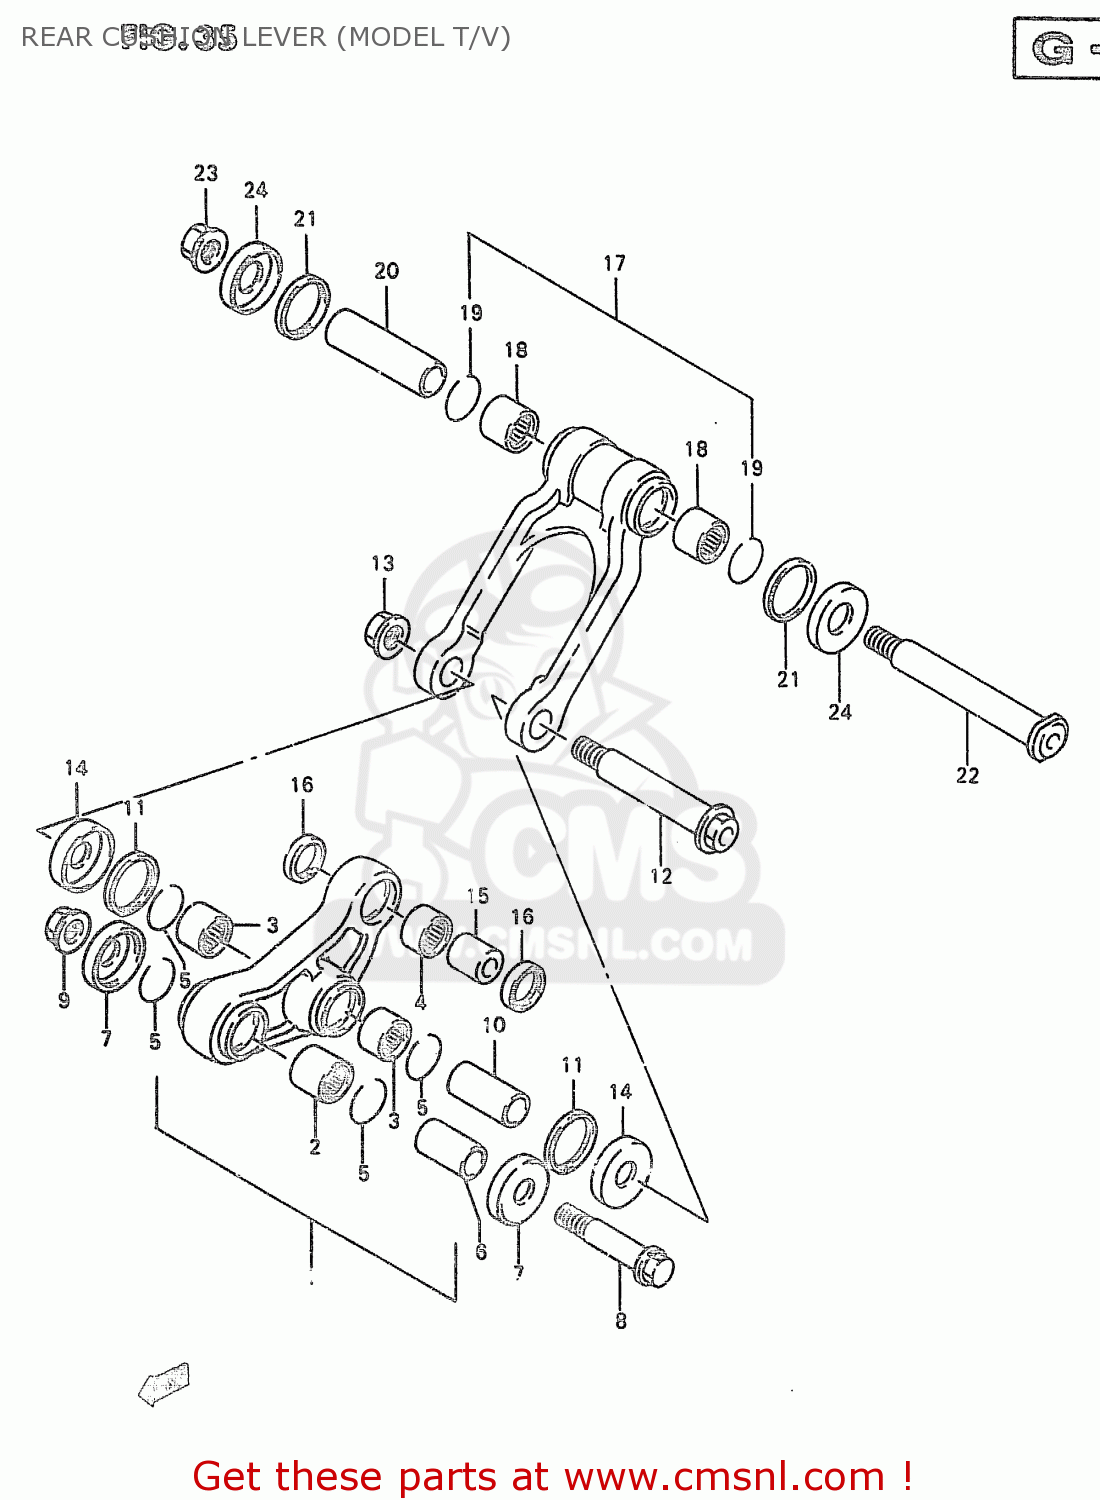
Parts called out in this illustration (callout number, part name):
1	LEVER SET,RR CUSHION
2	BEARING(20X27X25)
3	BEARING(22X28X20)
4	BEARING(20X26X12)
5	CIRCLIP
6	SPACER,RR CUSHION LEVER FR
7	SEAL,RR CUSHION LEVER FR DUST
8	BOLT,RR CUSHION LEVER FR
9	NUT 12MM
10	SPACER,RR CUSHION LEVER CTR
11	SEAL,RR CUSHION LEVER CTR
12	BOLT,RR CUSHION LEVER CTR
13	NUT
14	CAP,RR CUSHION LEVER CTR
15	SPACER,RR CUSHION LEVER RR
16	SEAL,OIL(20X26X4.5)
17	LEVER SET,REAR CUSHION
18	BEARING(22X28X20)
19	CIRCLIP
20	SPACER,RR CUSHION ROD
21	SEAL,RR CUSHION LEVER CTR
22	BOLT,RR CUSHION ROD
23	NUT
24	CAP,RR CUSHION LEVER CTR
